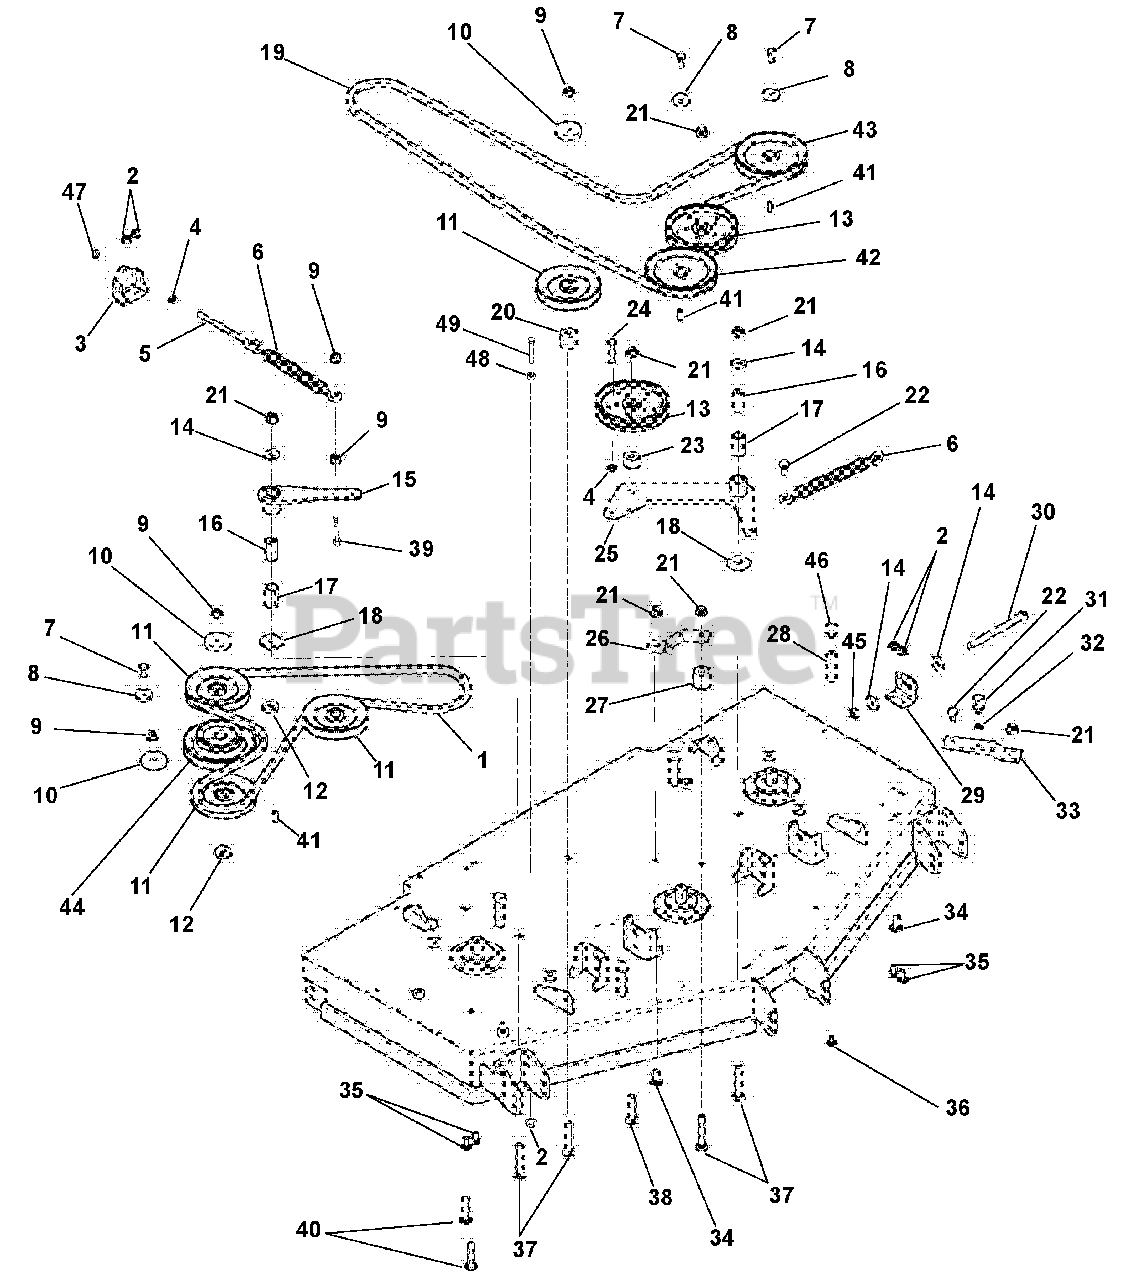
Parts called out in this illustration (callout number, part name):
1	Belt, BB
2	Nut, Locking Nylon Flange .38-16
3	Bracket, Spring Mount
4	Nut, Hex Jam
5	Bolt, .38-16 x 6.00 .62 Diameter Eye
6	Spring, Extension
7	Bolt, Hex .38-16 x 2.75 Grade 8
8	Retainer, Sheave
9	Nut, Locking Top Flange .50-13
10	Cap, Idler Bearing Sealing
11	Sheave, .50" ID x 6.00" OD V-Idler
12	Spacer, .516 x 1.5 x .2894
13	Pulley, Idler Flat 6.75 x .510
14	Washer, Flat Steel .563 x 1.38 x .109
15	Arm, Idler Pivot
16	Bushing, Spacer .502 x .997 x 2.03
17	Bushing, 1.00 x 1.125 x 1.936
18	Washer, Flat .640 x 1.75 x .250
19	V-Belt, HB, Wrapped Clutching
20	Spacer, .516 x 1.5 x 1.345
21	Nut, Locking Nyloc Flange .50-13
22	Bolt, Shoulder EP .38-16 x .30 Hex
23	Spacer, .516 x 1.5 x .97
24	Bolt, Hex .38-16 x 2.25
25	Arm, Idler Pivot
26	Bracket, Idler Mount
27	Spacer, .516 x 1.50 x 1.517
28	Nut, Coupling .31-18 x 3.00
29	Bracket, Spring Mount, Left Hand
30	Bolt, .5-13 x 7.00
31	Trunnion, Spring Adjust .50-13
32	Snap Ring, Retaining External .500 x .050
33	Arm, Spring Tensioner
34	Bolt, Round Head Square Neck .50-13 x 1.25
35	Bolt, Round Head Square Neck .38-16 x 1.00
36	Bolt, Round Head Square Neck .31-18 x .75 Loctite
37	Bolt, Round Head Square Neck .50-13 x 3.50
38	Bolt, Round Head Square Neck .50-13 x 2.75
39	Bolt, Hex .50-13 x 2.50
40	Bolt, Round Head Square Neck .50-13 x 2.50
41	Key, Square .25 x .25 x 1.00
42	Pulley, Double 1.0 x 6.75 O.D.
43	Pulley, "V" 1.0 x 6.75 O.D.
44	Pulley, Double 1.0 x 6.75 x 4.25
45	Nut, Jam .50-13
46	Bumper, Rubber
47	Nut, Locking Center Jam .375-16
48	Nut, Spin Lock Flange .375-16
49	Bolt, Hex .38-16 x 3.50 Grade 5
